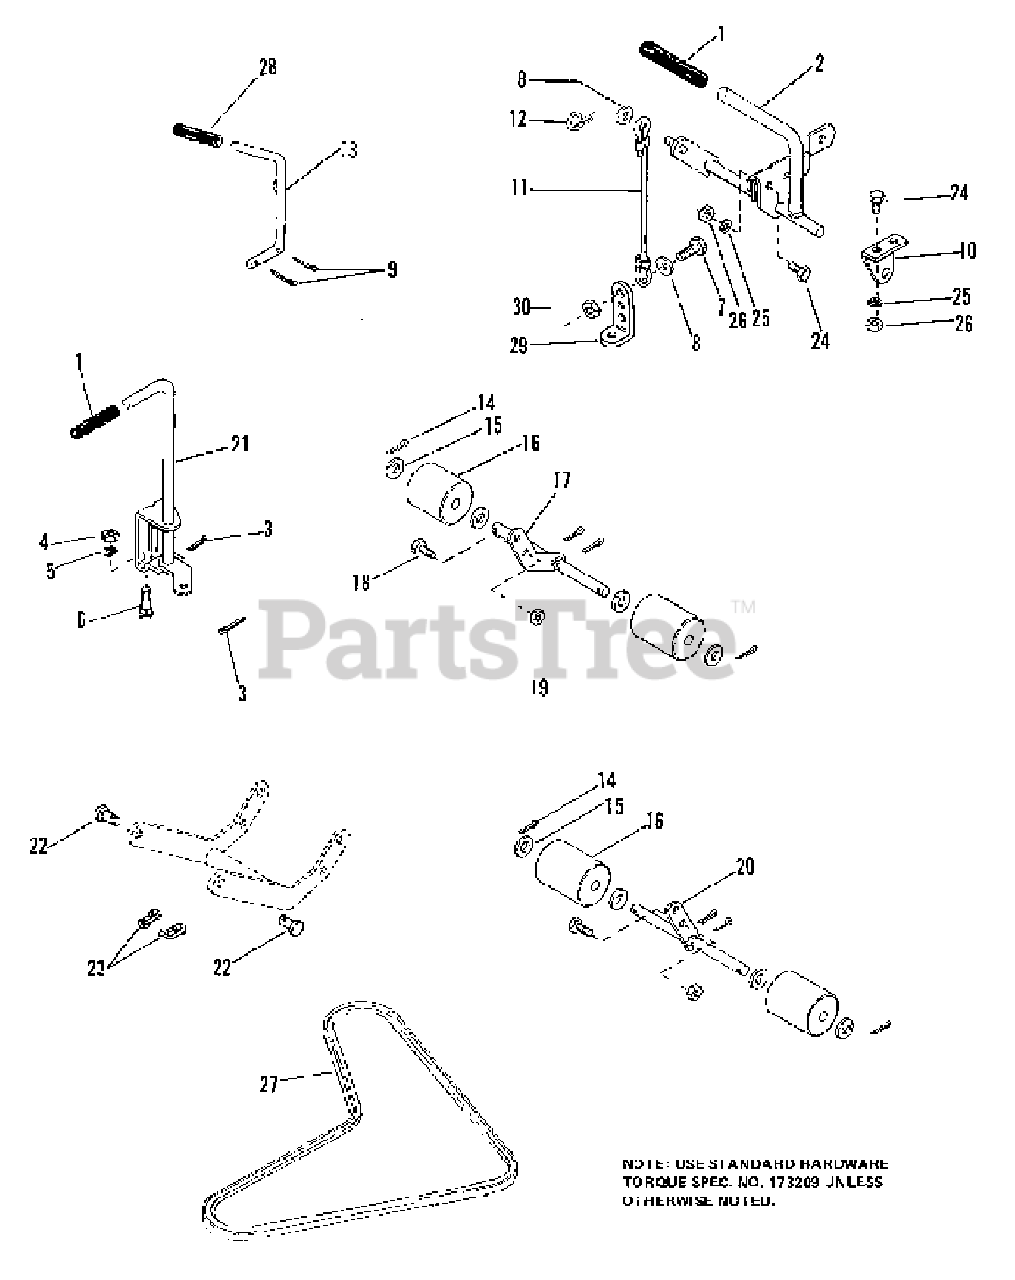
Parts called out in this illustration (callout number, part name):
1	GRIP, Handle
2	CLUTCH ARM ASSEMBLY
3	PIN, Cotter, 3/32 x 3/4
4	NUT, Hex, 5/16-18
5	LOCKWASHER, 5/16
6	BOLT, Carriage, 5/16-18 x 3/4
7	CAPSCREW, 5/16-18 x 3/4
8	WASHER, Plain, 5/16
9	PIN, Cotter, 3/32 x 1
10	SUPPORT, Clutch
11	CABLE, Mower Lift
12	CLIP, Spring
13	HANDLE, Control
14	PIN, Cotter
15	WASHER, Plain
17	R.H. ROLLER SHAFT ASSEMBLY
18	CAPSCREW, 3/8-16 x 1
19	NUT, Hex, Lock, 3/8-16
20	L.H. ROLLER SHAFT ASSEMBLY
21	CLUTCH LEVER ASSEMBLY
23	CLIP, Spring
24	CAPSCREW, 1/4-20 x 5/8
25	LOCKWASHER, 1/4
26	NUT, Hex, 1/4-20
27	BELT, V
28	GRIP, Handle
29	CLIP, Mower Lift
30	LOCKNUT, 5/16-18
